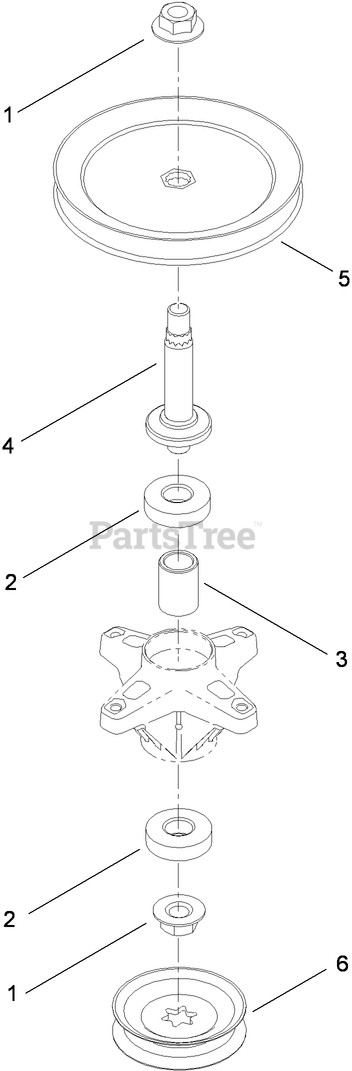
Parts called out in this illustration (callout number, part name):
1	NUT-LOCK, FLANGE
2	BEARING-BALL
3	SPACER
4	SHAFT-SPINDLE
5	PULLEY-DECK, 7 INCH
6	PULLEY-3.75 INCH
